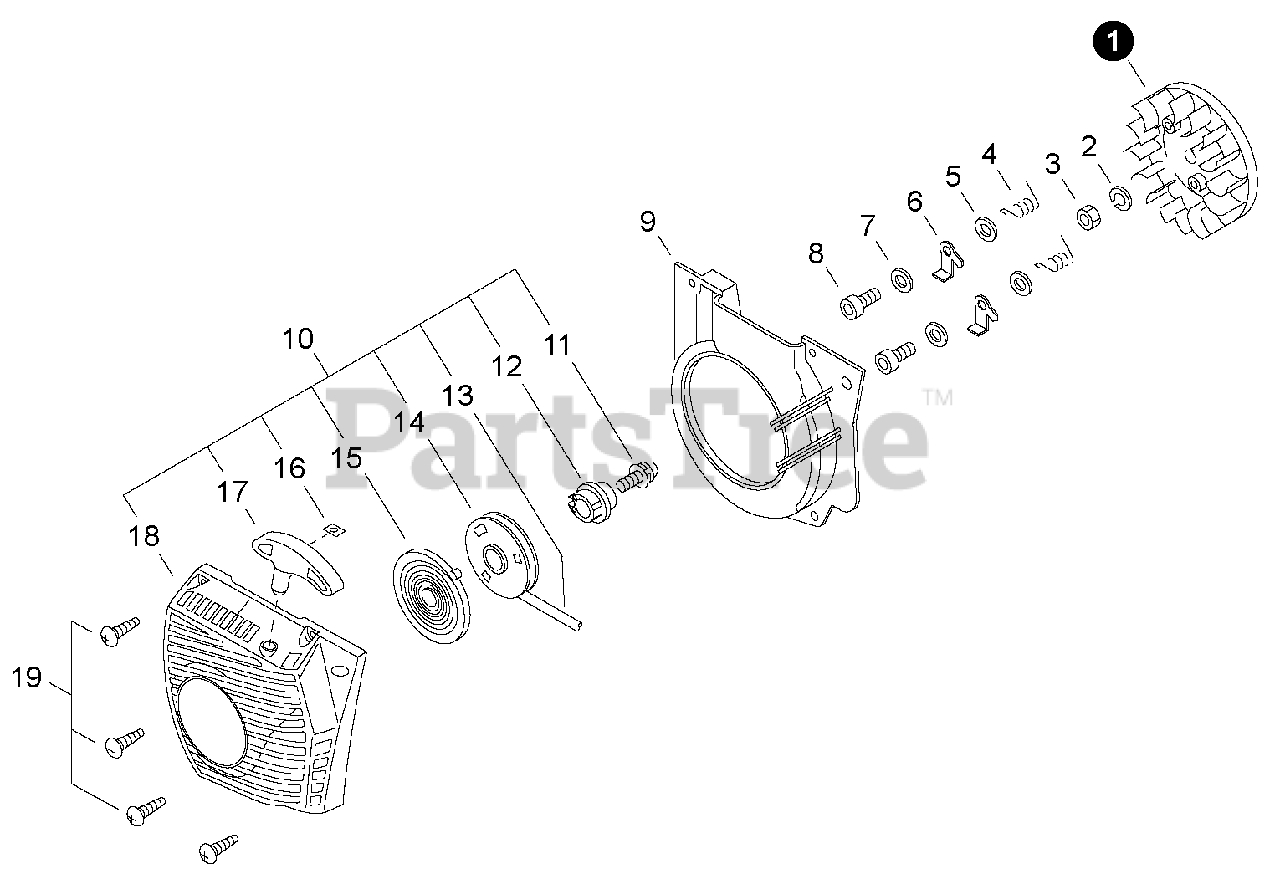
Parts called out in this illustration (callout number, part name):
1	FLYWHEEL
2	LOCKWASHER - 8
4	SPRING, RETURN
6	PAWL, STARTER
7	WASHER - 5
8	SCREW - 5X14
9	SHIELD, FAN
10	STARTER ASSY
12	CATCHER, PAWL
13	ROPE, STARTER
14	REEL, ROPE
16	RETAINER, ROPE
17	GRIP, STARTER
18	CASE, STARTER
19	SCREW - 4X16
